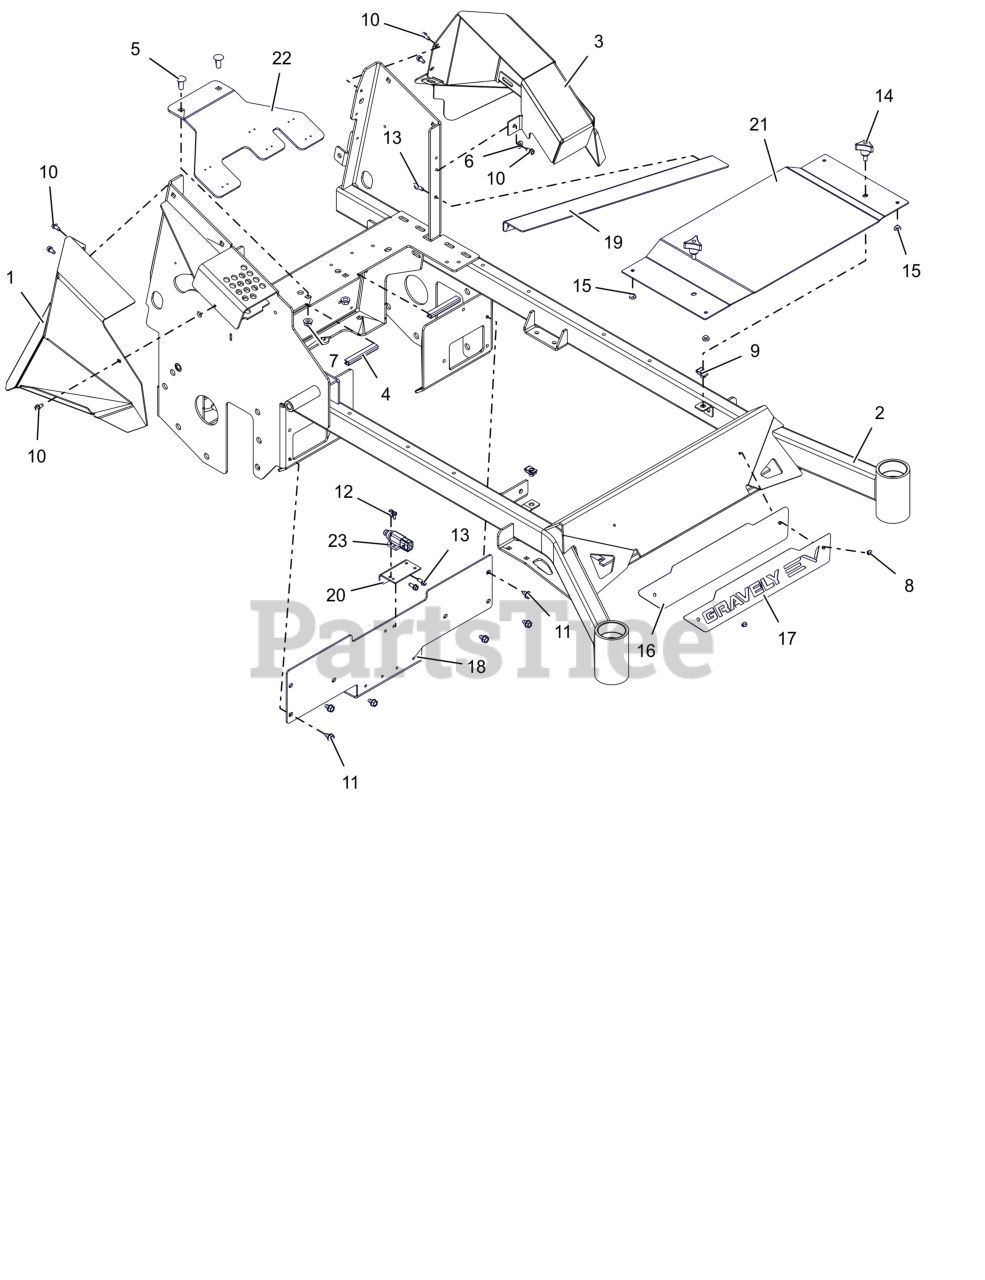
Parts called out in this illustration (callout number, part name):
1	WLDMT- RH FENDER
2	WLDMT- PROSTANCE MAIN FRAME
3	WLDMT- LH FENDER
4	STRIP, COWL
5	BLT,RHSSN .38-16X1.00 G5 ZCC
6	WSHR,FLT .344X.688X.065 ZCC
7	NUT-LK-CTR-FLG .375-16 GF ZCC
8	RVT, POP .187x.250 MULTIGRIP AL
9	NUT-CLIP RETAINER 5/16-18X.56
10	SCR-TAP .25-20X.50 HWH ZCC
11	SCR,TAP .312-18X.50 HWH TR ZCC
12	SCR,TAP #10-24X.50 HWH TR ZCC
13	SCR,TAP .25-20X.625 HWH ZCC
14	KNOB,WING STUD 5/16-18 X .75
15	BUMPER GROMMET
16	PLATE, BACK - GRAVELY (BLACK)
17	PLATE, LOGO - GRAVELY EV (RED)
18	PLATE- FRONT FRAME
19	BRKT, DRIP EDGE (BLACK)
20	BRKT- LOWER BRAKE RELEASE
22	BRKT, ANDERSON MTG (RED)
23	SWITCH, SEALED PLUNGER
